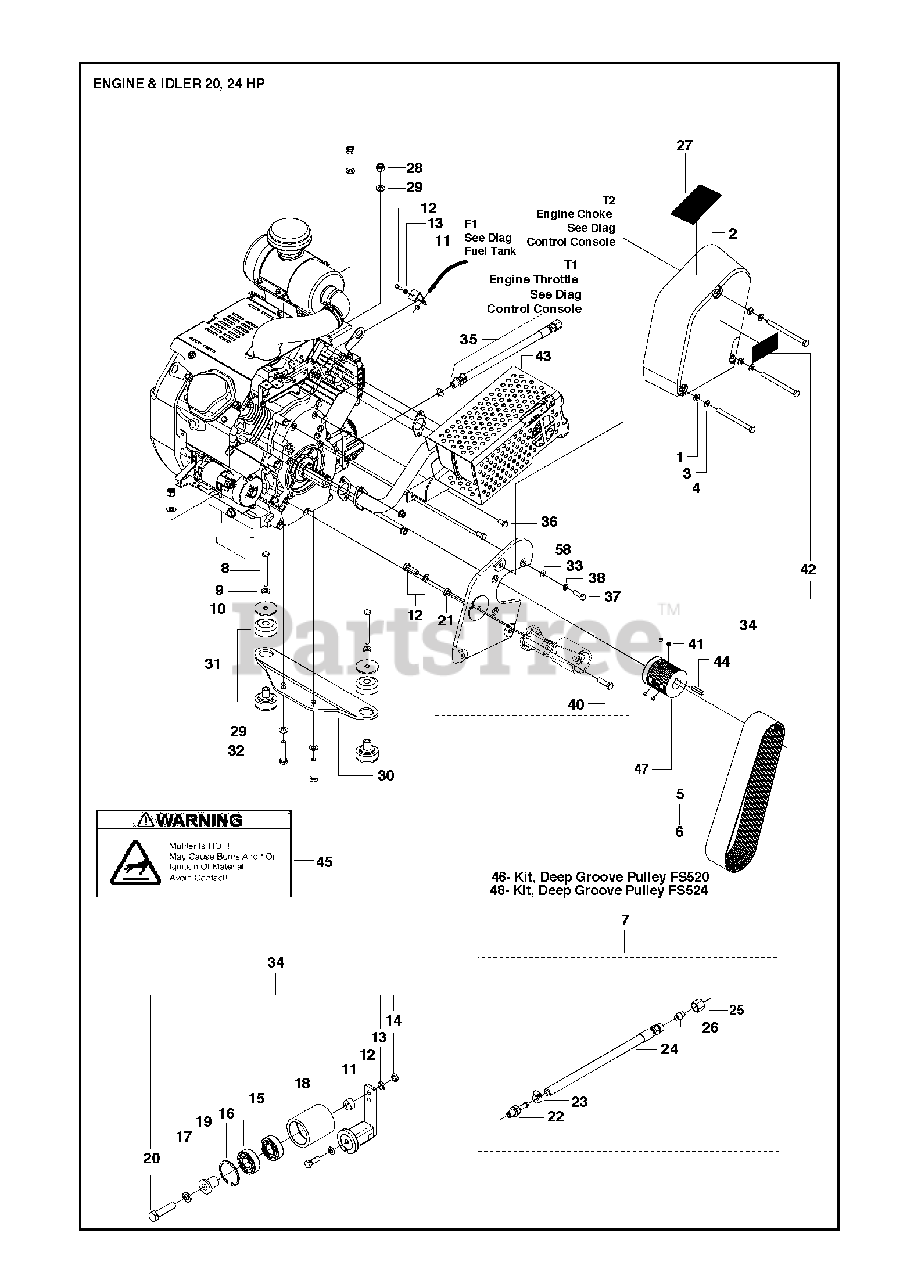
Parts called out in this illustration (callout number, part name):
1	WASHER
3	SPRING WASHER
17	WASHER
23	CLAMP, HOSE, MAH-4 FUEL LINE
28	HEXAGON LOCKING NUT
29	WASHER
33	WASHER
36	SCREW EHHM
38	SPRING WASHER
